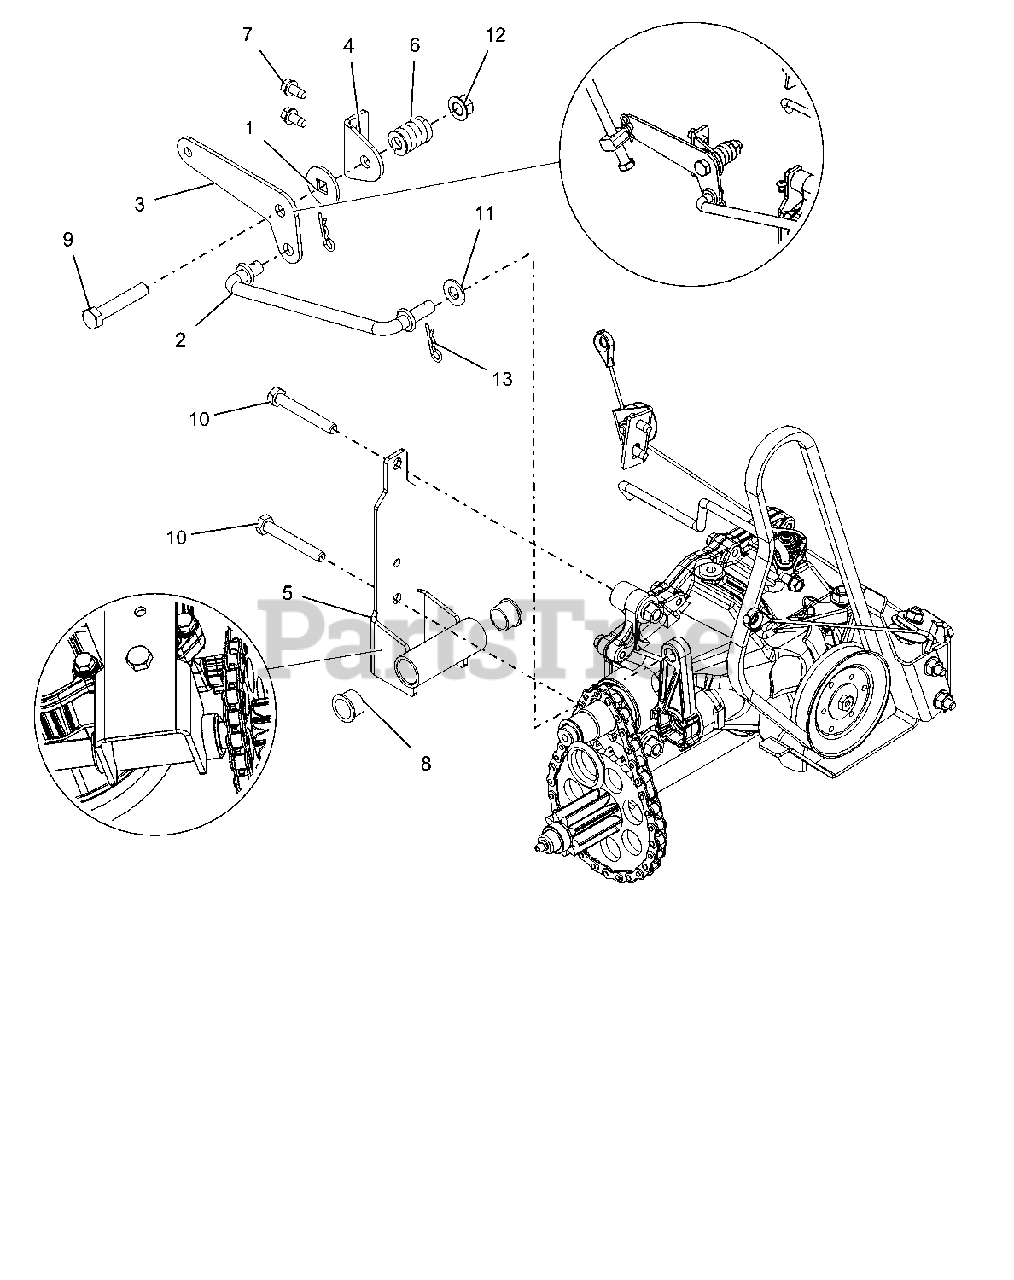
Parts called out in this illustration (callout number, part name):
1	FRICTION WASHER
2	ROD, HYDRO TRANS SHIFT
3	PIVOT, HYDRO TRANS SHIFT
4	BRACKET, HYDRO SHIFT PIVOT
5	TRANS MOUNT, TENSIONING, WHEEL
6	SG-COMP .187X.56X1.62
7	SCR-TAP .25-20X.50 HWH TR YWZ
8	BSHG-FLG .625X.750X.500X.875
9	@BLT-HEX .38-16X2.00 GR5 YWZC
10	@BLT-HEX .31-18X2.25 GR5 YWZC
11	@WSHR-FL-STL.406X.812X.065 YWZ
12	@NUT-LK-TOP-FLG .38-16 YWZC
13	PIN-HAIR INT .08X.18X1.18 YWZC
